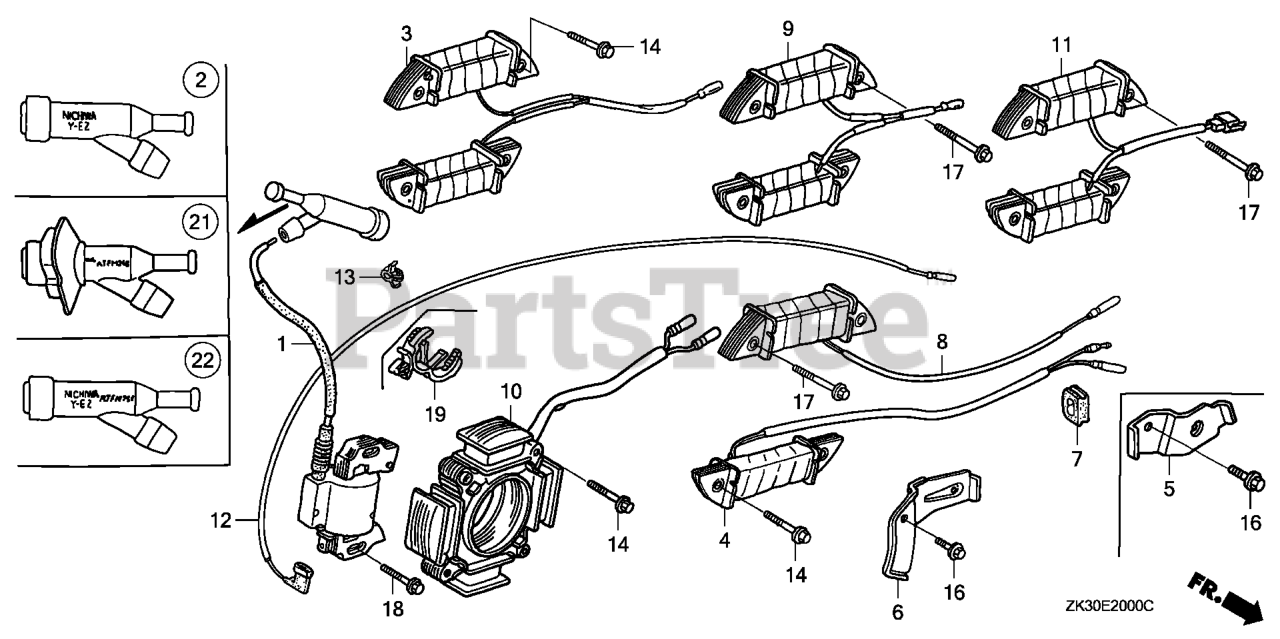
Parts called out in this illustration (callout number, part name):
1	COIL ASSY., IGNITION
6	CLAMP, WIRE
7	GROMMET, WIRE
11	COIL ASSY., CHARGE (10A)
12	WIRE, STOP SWITCH (430MM)
14	BOLT, FLANGE (6X40)
16	BOLT, FLANGE (6X12) (CT200)
17	BOLT, FLANGE (6X40)
18	BOLT, FLANGE (6X28) (CT200) Use up to Engine SN 1530314.
22	CAP ASSY., NOISE SUPPRESSOR (Honda Code 3526837). (NICHIWA Y-EZ RTFM256)
